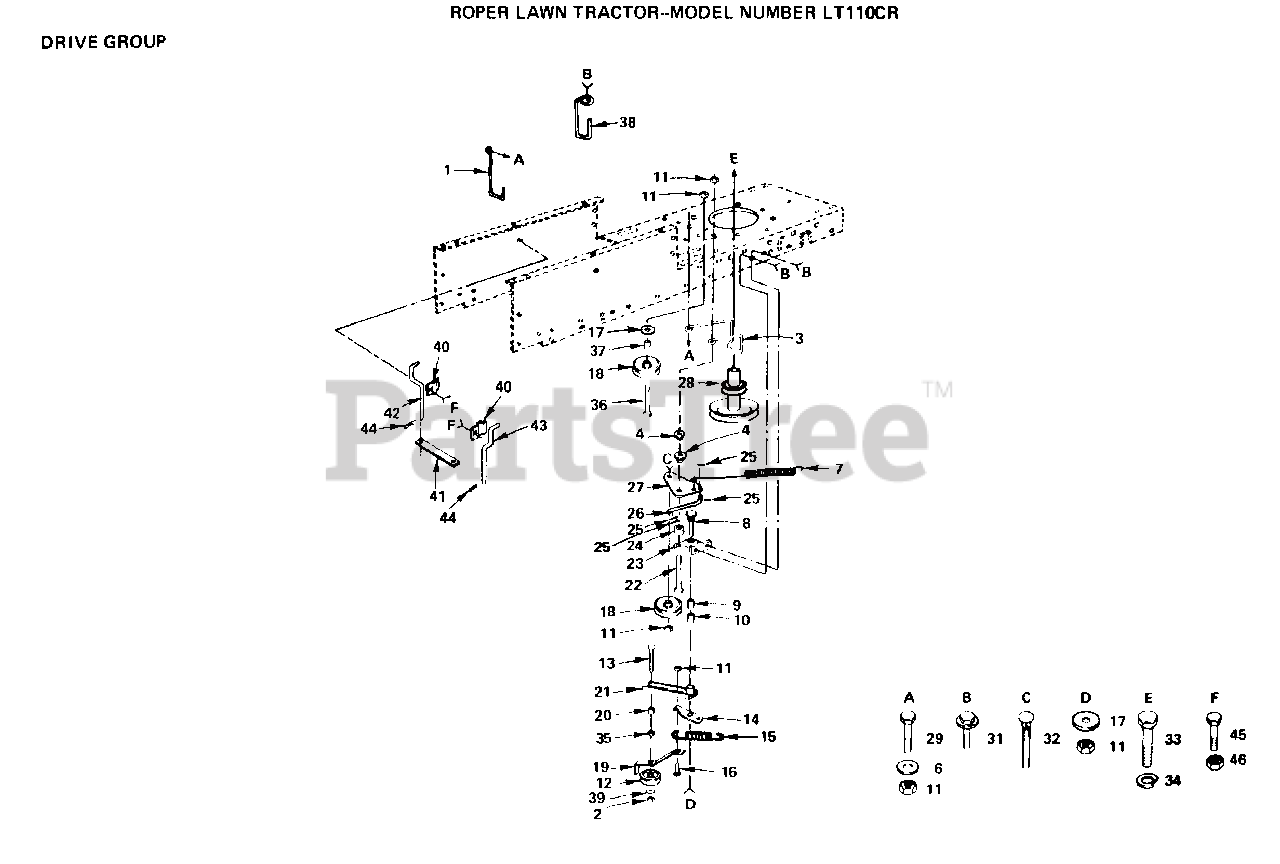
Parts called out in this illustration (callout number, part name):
3	GUIDE BELT PLY LT
6	WASHER
7	SPRING CLUTCH LT
8	BOLT
12	IDLER.FLAT.GTV
13	BOLT
15	SPRING EXT LT
16	BOLT
17	WASHER
18	IDLER-FLAT LT
21	ARM IDLER ASSY LT
23	BRACKET SUPT LT
24	SPACER LT
25	COTTER PIN
29	BOLT
31	SCREW
32	BOLT
34	LOCKWASHER
35	NUT.HEX.3/8-16UNC
36	BOLT
37	SPACER SPLIT LTV
39	WASHER
40	CLAMP LT
43	KEEPER BELT RH
44	SPRING.RETAINER
45	BOLT
